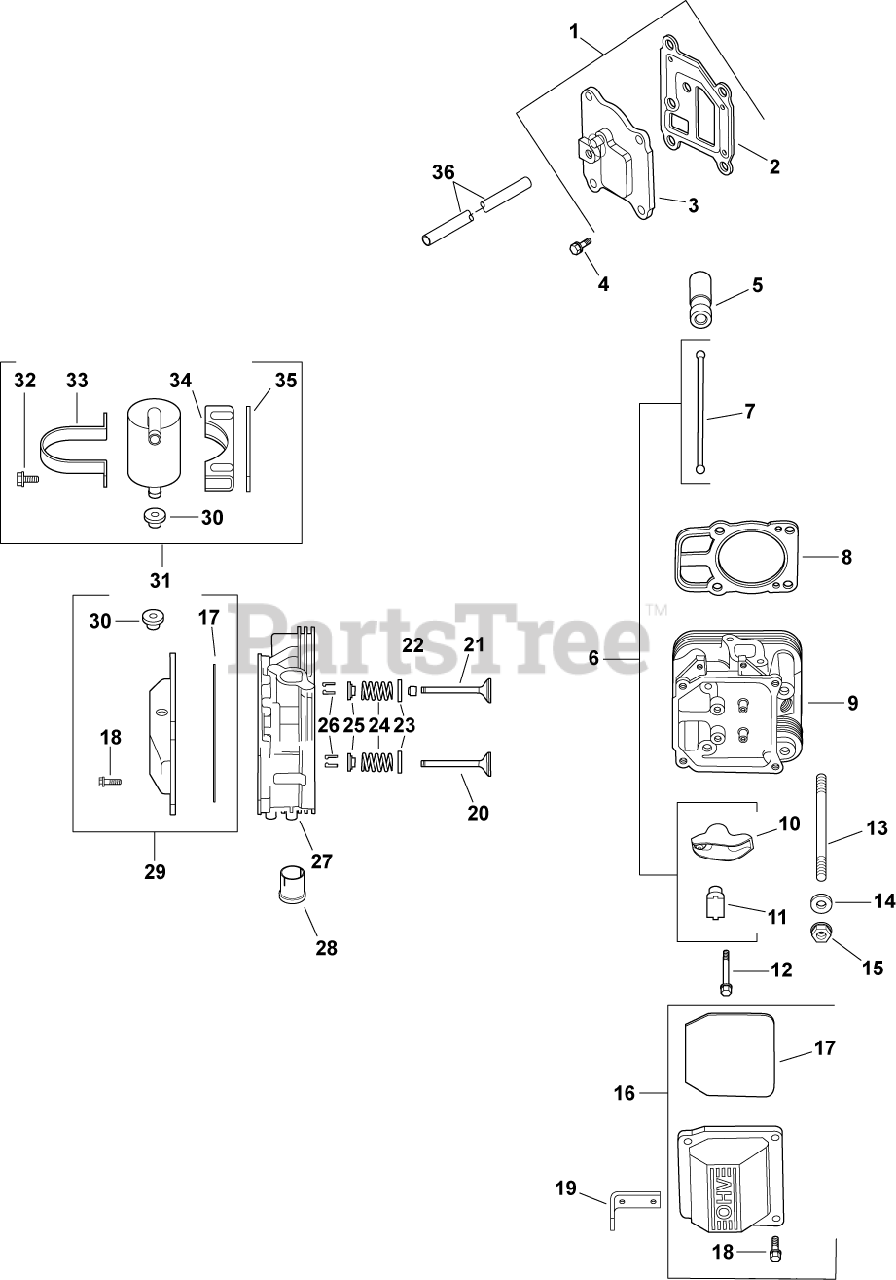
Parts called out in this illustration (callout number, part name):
1	KIT, BREATHER COVER W/GASKET
2	GASKET, BREATHER-USE 24 041 67-S
3	COVER, BREATHER -USE 24 096 125-S
4	SCREW,FLG THD FRM M6X1.0X20-(#25086396S)
5	LIFTER, HYDRAULIC VALVE-USE 25 351 10-S
6	KIT, VALVE TRAIN
7	ROD, PUSH
8	CYL HEAD GASKET KIT-USE 24 841 04-S
9	HEAD, ASSEM CYLINDER #2 -USE 24 318 116-
10	ARM, ROCKER
11	PIVOT, ROCKER ARM
12	SCREW, FLG M6X1.0X34
13	STUD, M8X1.25
14	WASHER, FLAT 8.6 MM
15	NUT, FLG M8X1.25
16	KIT, VALVE COVER-PLAIN
17	O-RING (YELLOW), VALVE COVER
18	SCREW, FLG M6X1.0X30
19	STRAP, LIFTING-USE 25 445 03-S
20	VALVE, EXHAUST (STD) - USE 32 016 01-S
21	VALVE, INTAKE (STD)
22	SEAL, VALVE STEM - (#2503214S)
23	RETAINER, SPRING
24	SPRING, VALVE
25	RETAINER, VALVE SPRING - USE 25 173 28-S
26	KIT, RETAINER
27	HEAD, ASSEM CYLINDER #1 -USE 24 318 108-
28	LINER, EXHAUST PORT-USE 24 605 07-S
29	KIT, VALVE COVER
30	GROMMET, RUBBER
31	KIT, BREATHR SEPARATR-(#24755241S)
32	SCREW,FLG THD FRM M5X0.8X16-(#25086398S)
33	STRAP, BREATHER - USE 24 755 241-S
34	BRACKET, BREATHER SEPARATOR
35	SPACER
36	HOSE, BREATHER-USE 24 326 63-S
2401602-S	VALVE, EXHAUST (.25)
2401702-S	VALVE, INTAKE (.25)
